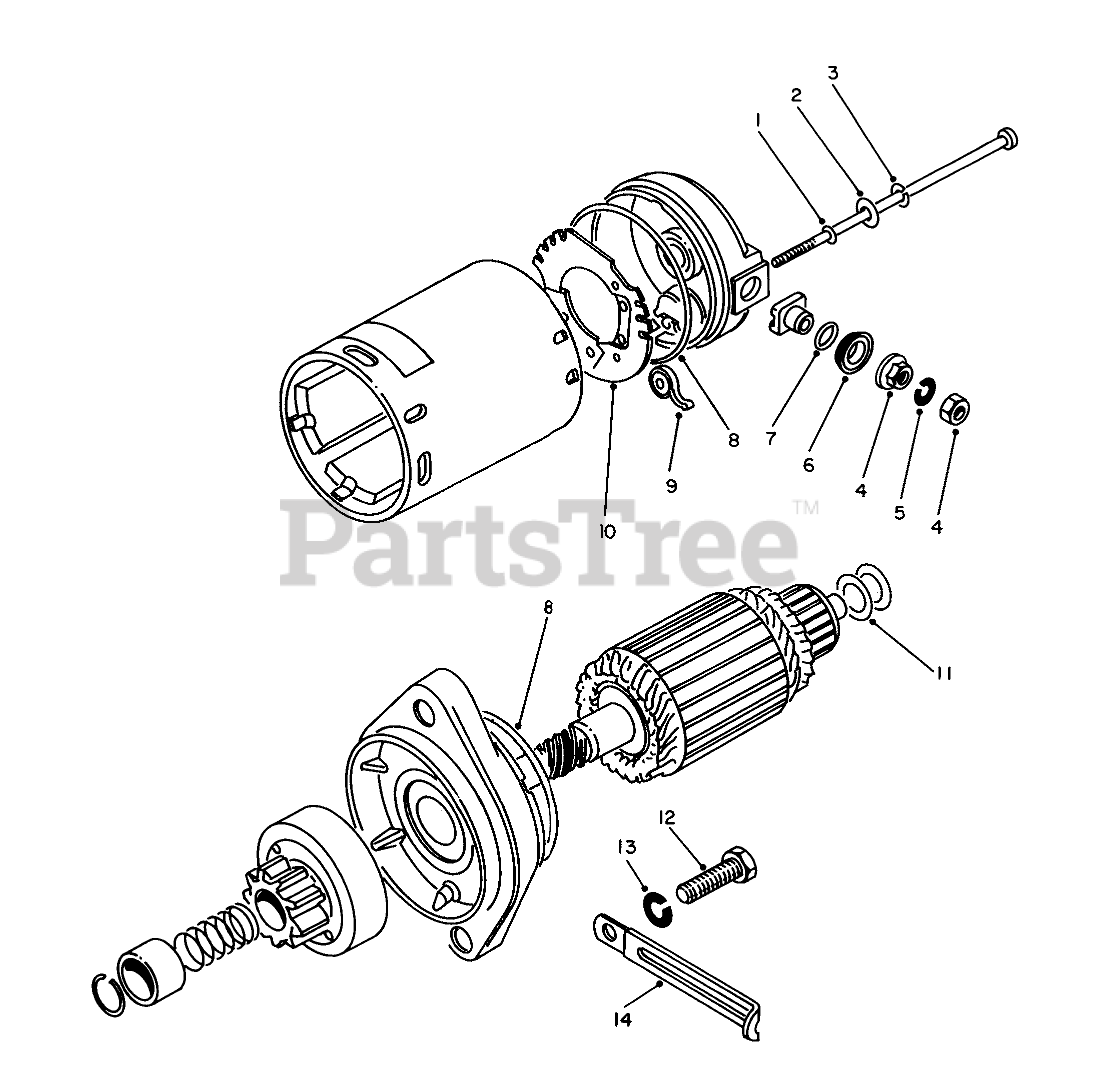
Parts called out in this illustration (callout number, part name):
1	0-Ring
2	Washer
3	Washer
5	LOCKWASHER
6	Bushing
7	0 Ring
8	0 Ring
9	Spring
10	Holder Assembly-Brush (Incl. Ref. #9)
13	Lockwasher
14	Clamp
